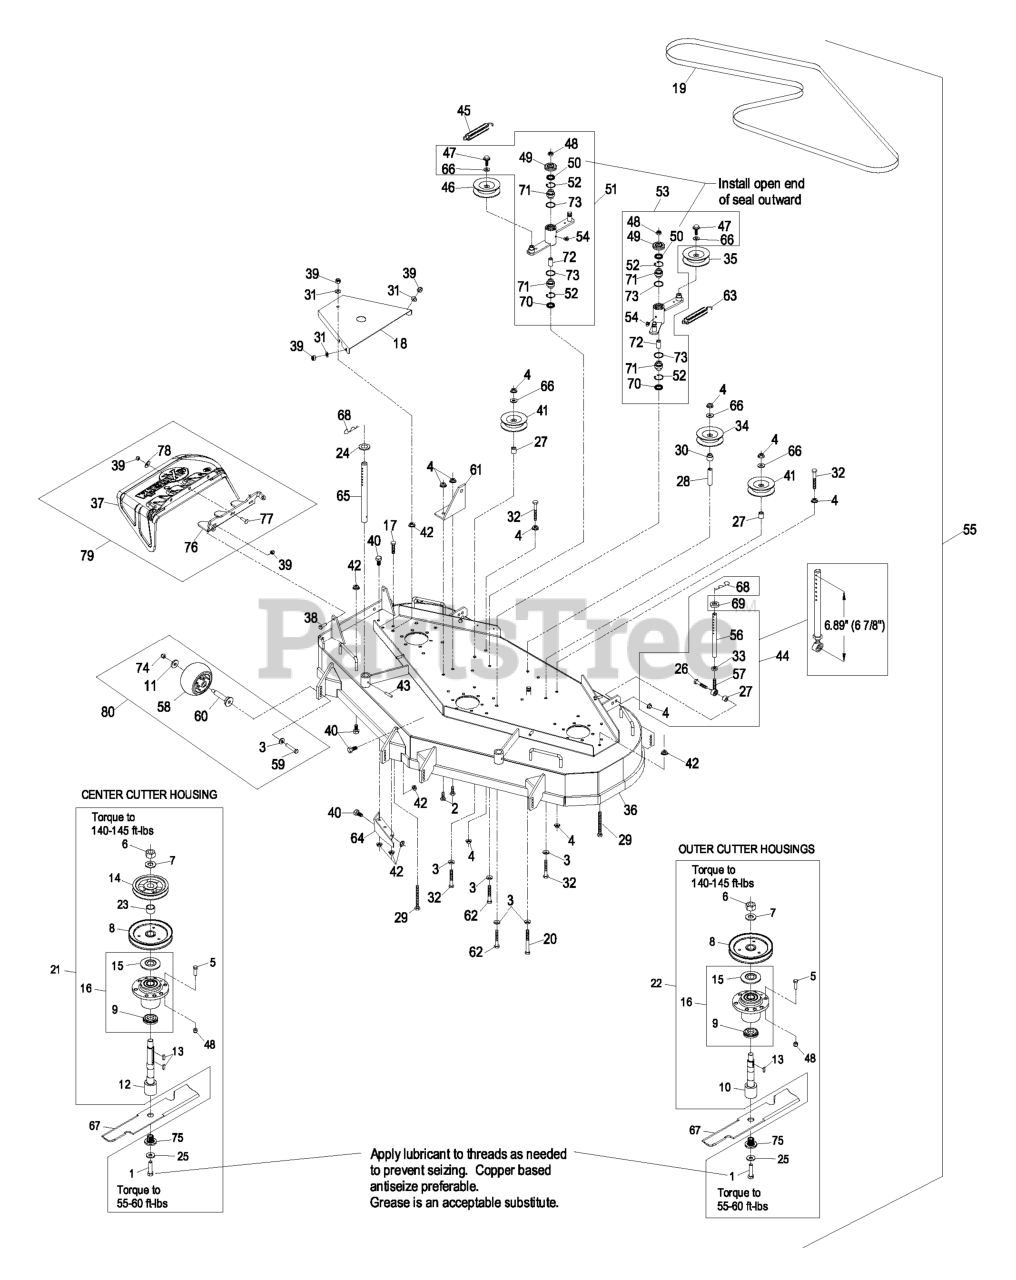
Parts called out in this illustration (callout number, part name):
1	SCREW-HH
2	SCREW-HH
3	WASHER-BELLEVILLE
4	NUT-HHF, WHIZ
5	SCREW-HH
6	NUT-HH
8	SHEAVE,BLADE DRIVE 6.30
9	SPACER-GUARD, BOTTOM
10	KIT, SPLINED SPINDLE 103-
12	KIT, SPLINED SPINDLE 103-
14	SHEAVE,MOWER DRIVE
15	GUARD-BEARING, TOP
16	KIT, CUTTER HOUSING
17	SCREW-HH
18	SHIELD,BELT SIDE FMD524
19	BELT,BLADE DRIVE FMD524
20	SCREW-HH
21	ASM,CUTTER HSG FMD524 CTR
22	ASM, CUTTER HSG COMPLETE
23	SPACER,TUBE
24	SPACER-DECK SUPPORT
25	WASHER-SPRING
26	SCREW-HH
28	SPACER-ANCHOR, CLUTCH
29	BOLT,TAP HH
30	BUSHING,IDLER
31	WASHER-FLAT
32	BOLT-CARR
33	NUT-HEX
34	PULLEY-IDLER
35	PULLEY-IDLER
37	CHUTE,DISCHARGE
38	SCREW-HH
39	NUT-LOCK, NI
40	SCREW-HH
41	IDLER,PULLEY
44	KIT,SUPPORT LINK W/PIN
45	SPRING-EXTENSION
46	IDLER,PULLEY
47	SCREW-HHF
48	NUT-LOCK, NI
49	GUARD-TOP
50	SEAL-LIP, SINGLE
51	KIT, IDLER ARM W/BEARINGS
52	RING-SNAP
53	KIT, IDLER ARM W/BEARINGS
54	FITTING-GREASE, 90 DEG
55	Asm, Complete Deck
56	LINK,SUPPORT
57	BALLJOINT
58	ROLLER-SCALP, ANTI
59	SCREW-HH
61	BRACKET,SPRING ANCHOR
62	SCREW-HH
63	SPRING-EXTENSION
64	WLD,BAFFLE DISCHARGE
65	ROD,DECK SUPPORT
66	WASHER-FLAT
68	PIN,HAIR COTTER
70	SEAL-LIP, DOUBLE
71	BEARING-SPHERICAL
72	BUSHING-LEVER, LIFT
74	NUT-LOCK, NI
75	BUSHING,SPLINED
76	BRACKET, DISCHARGE CHUTE
77	SCREW-CARR
78	WASHER-FLAT
79	ASM,FMD DISCHARGE CHUTE
